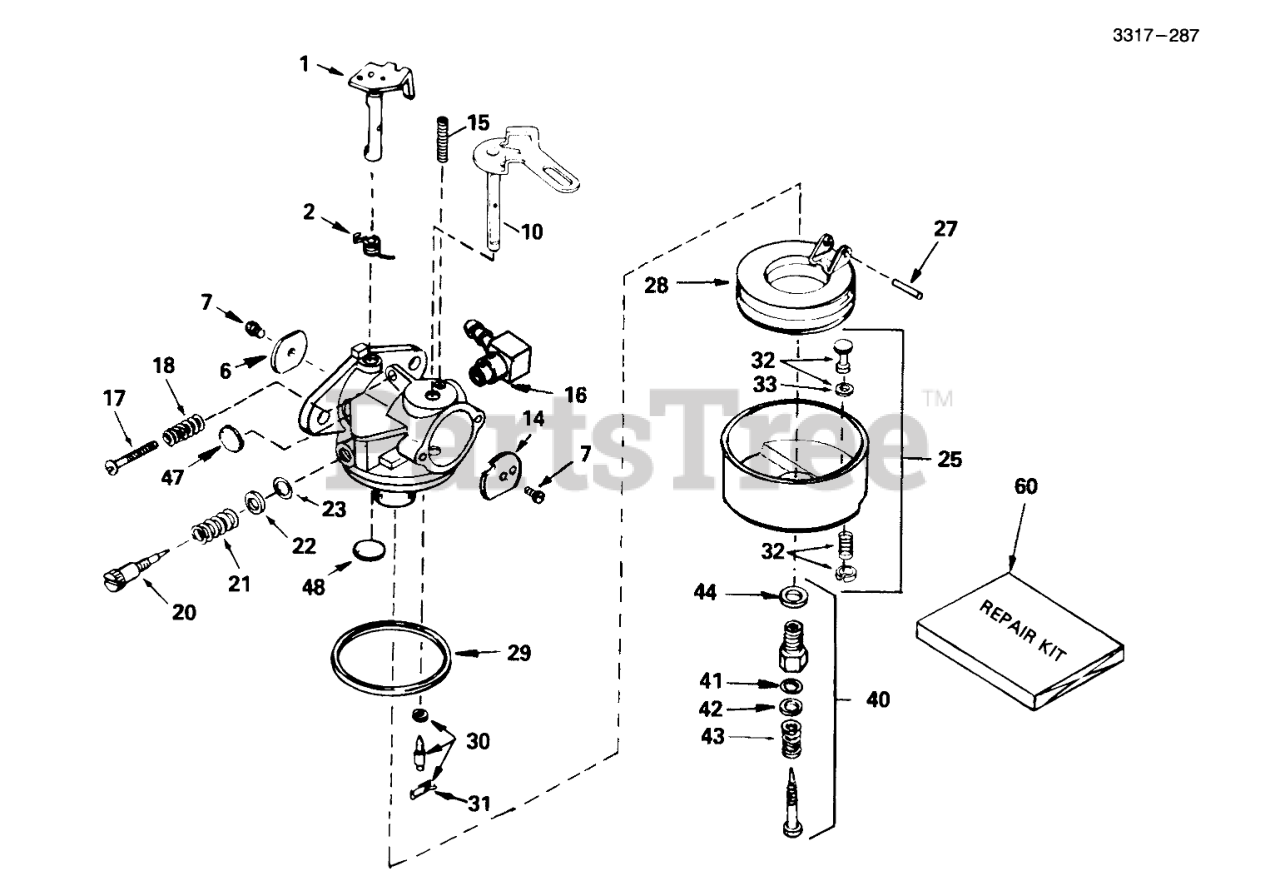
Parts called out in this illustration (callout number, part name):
1	Throttle Shaft and Lever ASM
2	Spring-Return, Throttle
6	Shutter-Throttle
7	Screw-Shutter
10	Choke Shaft and Lever Asm
14	Shutter-choke
15	Spring-Positioning, Choke
16	Fitting-Fuel
17	Screw-Throttle Crack Screw / Idle Speed
18	Spring-Tension
20	Screw-Idle
21	Spring-Tension
23	"O"Ring
25	Bowl-Assembly(Incl Ref. #32,33)
27	Shaft-Float
28	Float
29	O Ring-Bowl, Float
30	Inlet Needle-Seat & Clip(Incl Ref. #31)
31	Clip-Spring
32	Drain Assembly-Bowl(Incl Ref. #33)
33	Gasket-Plunger, Drain
40	Screw Adjustment Assembly(Incl Ref. #41-44)
41	"O"Ring
44	Washer-Bowl Nut
47	Plug-Welch, Idle Mixture Well
48	Plug-Welch, Atmospheric Vent
60	Kit-Repair
